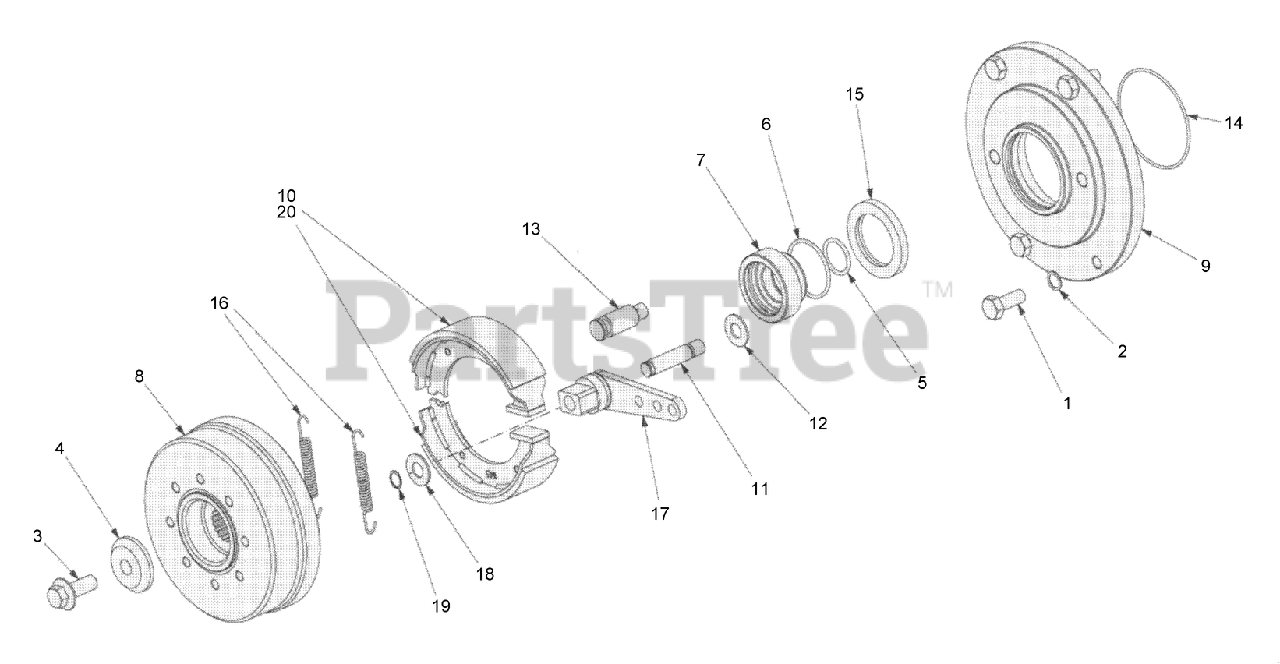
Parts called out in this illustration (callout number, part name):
2	Washer
4	WASHER-Pinion
5	O-RING
7	TRACK-Oil Gasket
8	DRUM-Brake
11	Pin
12	WASHER-Axial
13	Pin
14	O-RING
16	Spring
17	LEVER-Brake
18	WASHER-Split Lock, Brake
19	RING-Retainer
20	SHOE-BRAKE
